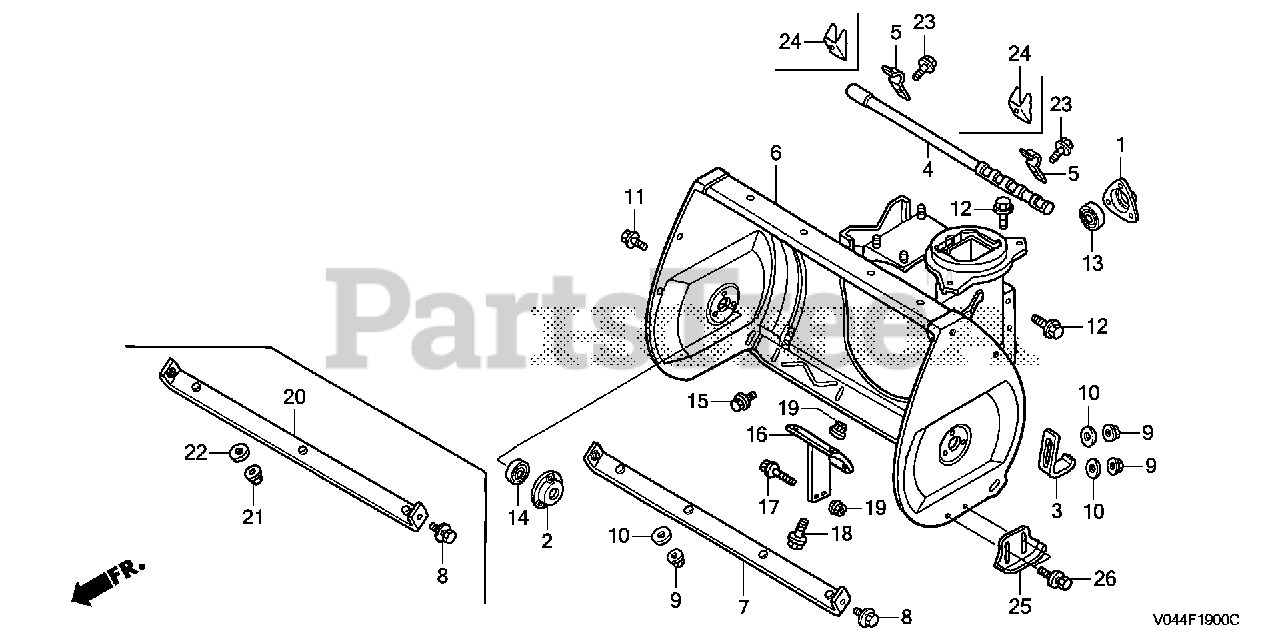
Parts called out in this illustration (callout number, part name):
1	HOLDER, WHEEL SHAFT BEARING
2	HOLDER, AUGER BEARING
3	SKID, AUGER
4	BAR, SNOW DROP
5	BRACKET, SNOW DROP BAR
6	HOUSING, AUGER
8	BOLT-WASHER (8X16)
9	NUT, FLANGE (6MM)
10	WASHER, PLAIN (6MM)
11	BOLT, FLANGE (6X12)
12	BOLT, FLANGE (8X16)
13	BEARING, RADIAL BALL (6004UU)
14	BEARING, RADIAL BALL (6203UU)
15	BOLT, FLANGE (6X12)
20	GUARD, AUGER HOUSING
21	NUT, FLANGE (8MM)
22	WASHER, PLAIN (8MM)
23	BOLT, FLANGE (6X8)
25	SKID, AUGER
26	BOLT-WASHER (8X16)
